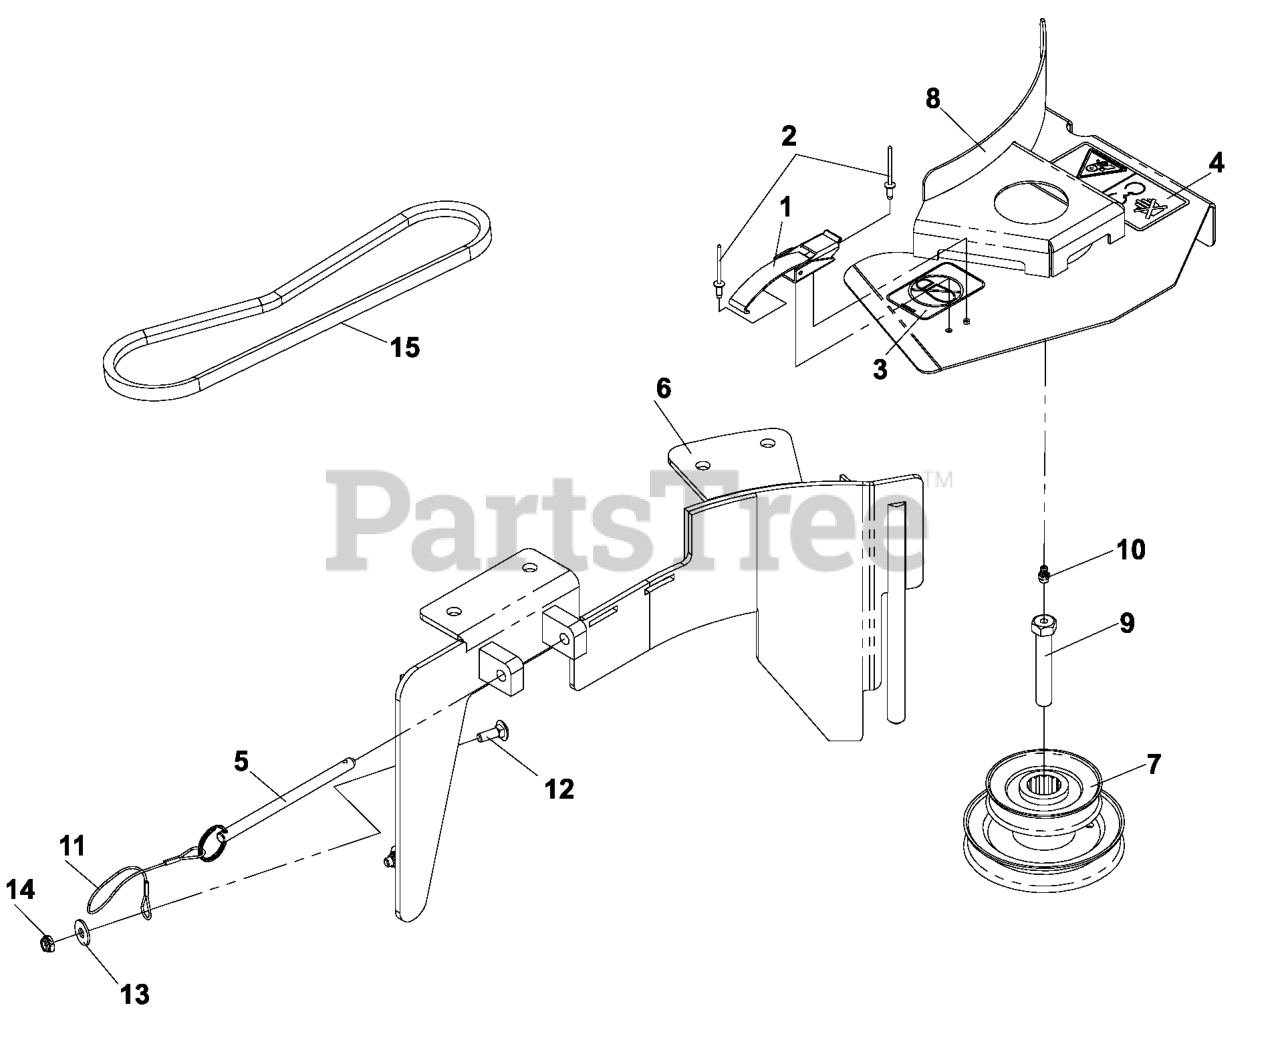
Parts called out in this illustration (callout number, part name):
1	DRAW LATCH
2	RIVET, BLIND, 5/32 DIA
3	DECAL, NO STEP
4	DECAL, BELT DRIVE
6	BLOWER DECK PLATE
7	42/48 LG DBL HEX STACK PULLEY
8	BELT SHIELD ASSY, 42"
9	DRILLED BOLT 7/16-20 X 2 1/2"
10	ZERK
12	RHSNB 1/4C X 3/4
13	WASHER 1/4 FLAT
14	JAM NUT 1/4C (2 2 PW01)
